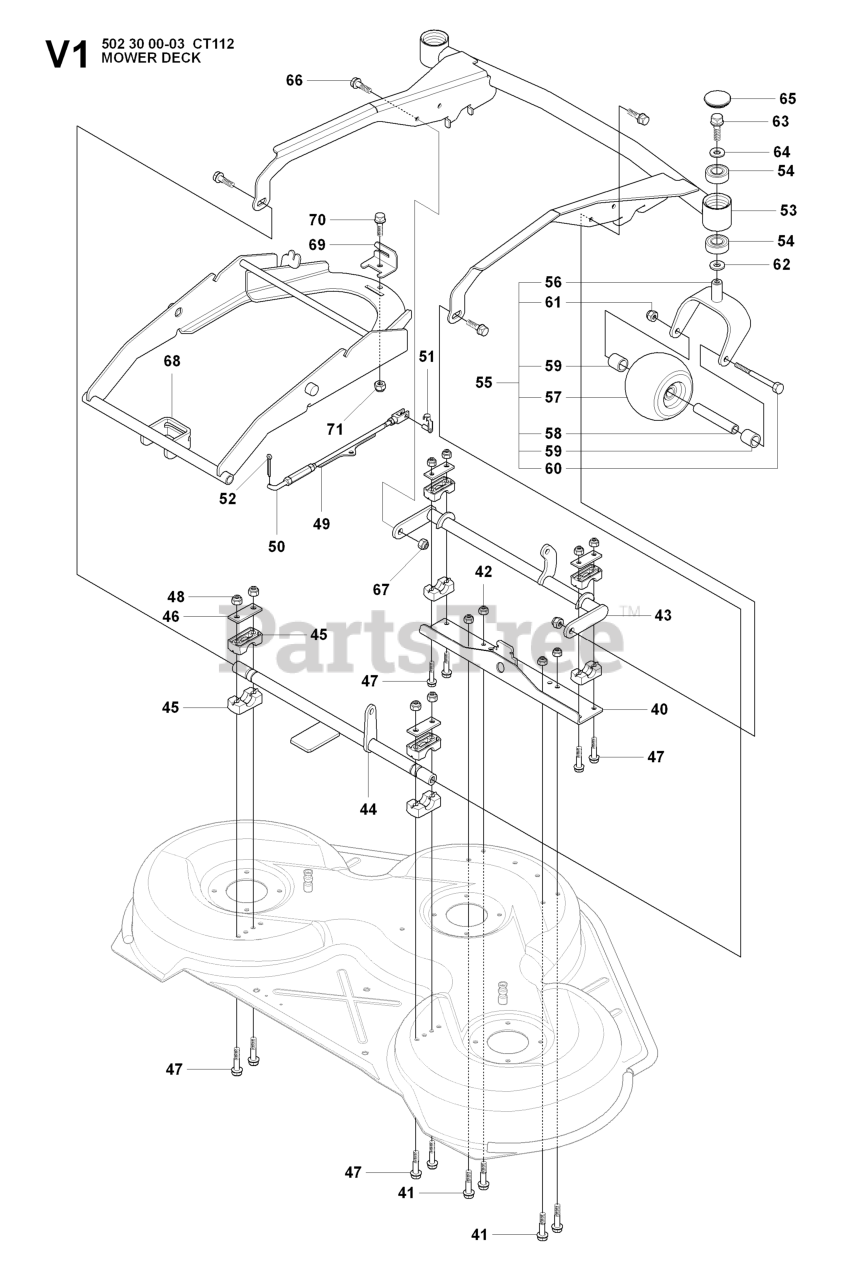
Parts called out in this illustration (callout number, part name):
42	LOCKNUT M8
48	LOCKNUT M8
50	PARALLEL ROD
54	BALL BEARING 6004-2RS1
55	PIVOT WHEELS
57	DECK ROLLER, FRONT
61	NUT
65	HUB CAP PIVOT WHEEL
67	LOCKNUT M8
71	LOCKNUT M8
